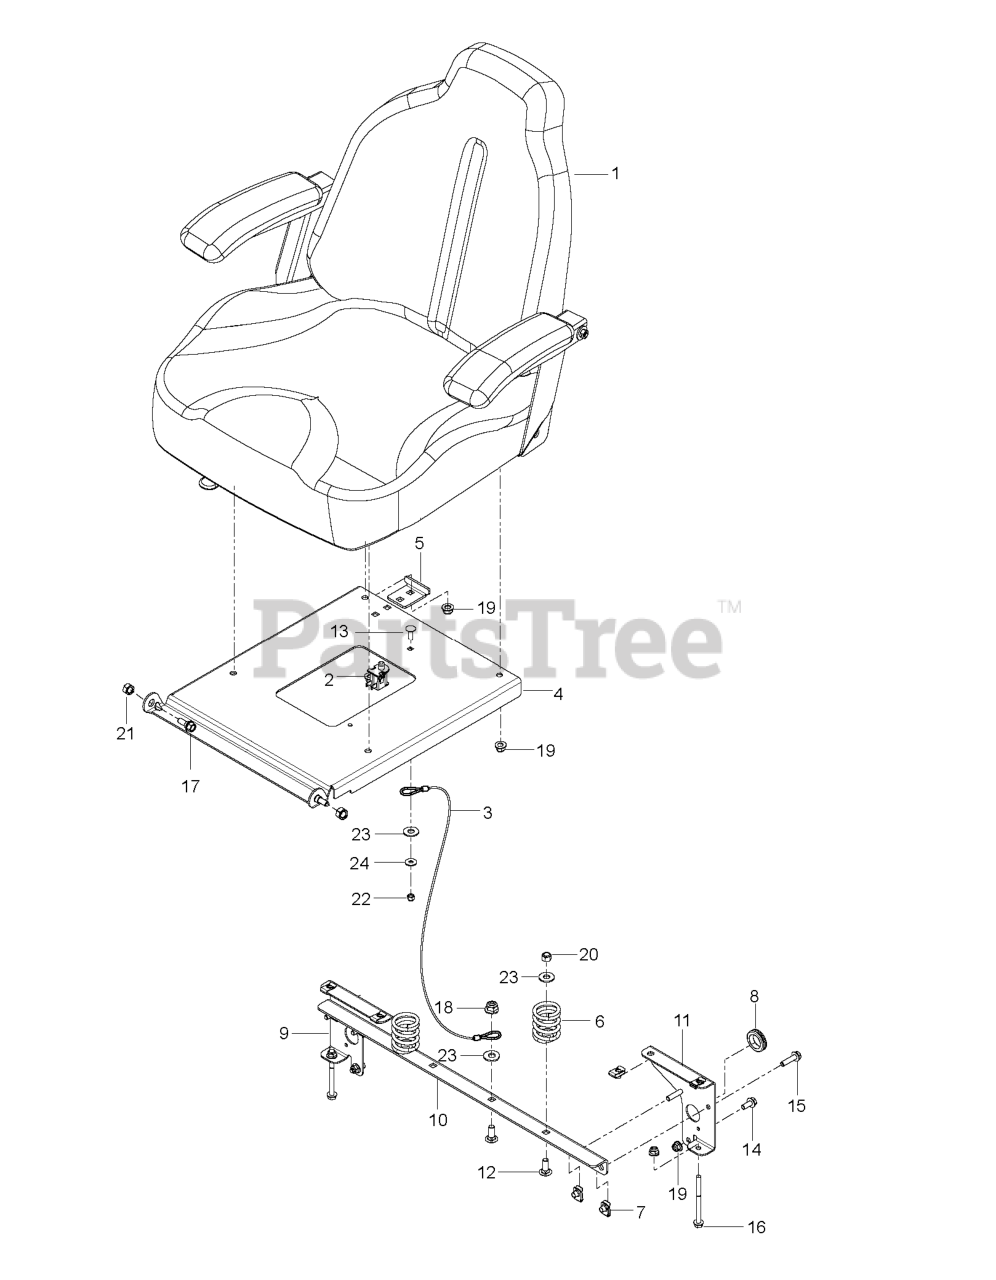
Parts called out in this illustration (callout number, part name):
1	SEAT.ASM.907.TRACK.W/O.BELT
2	SWITCH.INTRLCK.CLUTCH.
3	SEAT LANYARD
4	SUPPORT.SEAT.ORANGE
5	STOP, SEAT - BLACK
6	SPRING.COMPRESSION.SEAT.BLACK
7	U-CLIP 5/16-18 NUT RETAINER
8	RUBBER GROMMET
9	SUPPORT.LT.BLK
10	SUPPORT.SEAT. BLK
11	SUPPORT.RT.BLK
12	RHSNB 3/8C X 1
13	1/4-20X3/4 CARR BLT
14	HHFS 5/16-18 X 3/4
15	HHFS 5/16-18 X 1.25 TPBLT GD 5
16	BOLT.HEX.FLNG.5/16-18X3.75
17	SB 5/16-18 HEX HD GD5, BLK ZN
18	NUT 3/8-16 HEX FLG NYLOC ZD
19	5/16-18 NYLOC FLANGE NUT
20	NUT 3/8-16 NYLOC
21	NUT.71038.31-18.HEX.NYLOCK
22	NUT.1/4-20.HEX.NYLOC.ZD
23	RP WASHER 3/8 FLAT
24	WASHER PM
